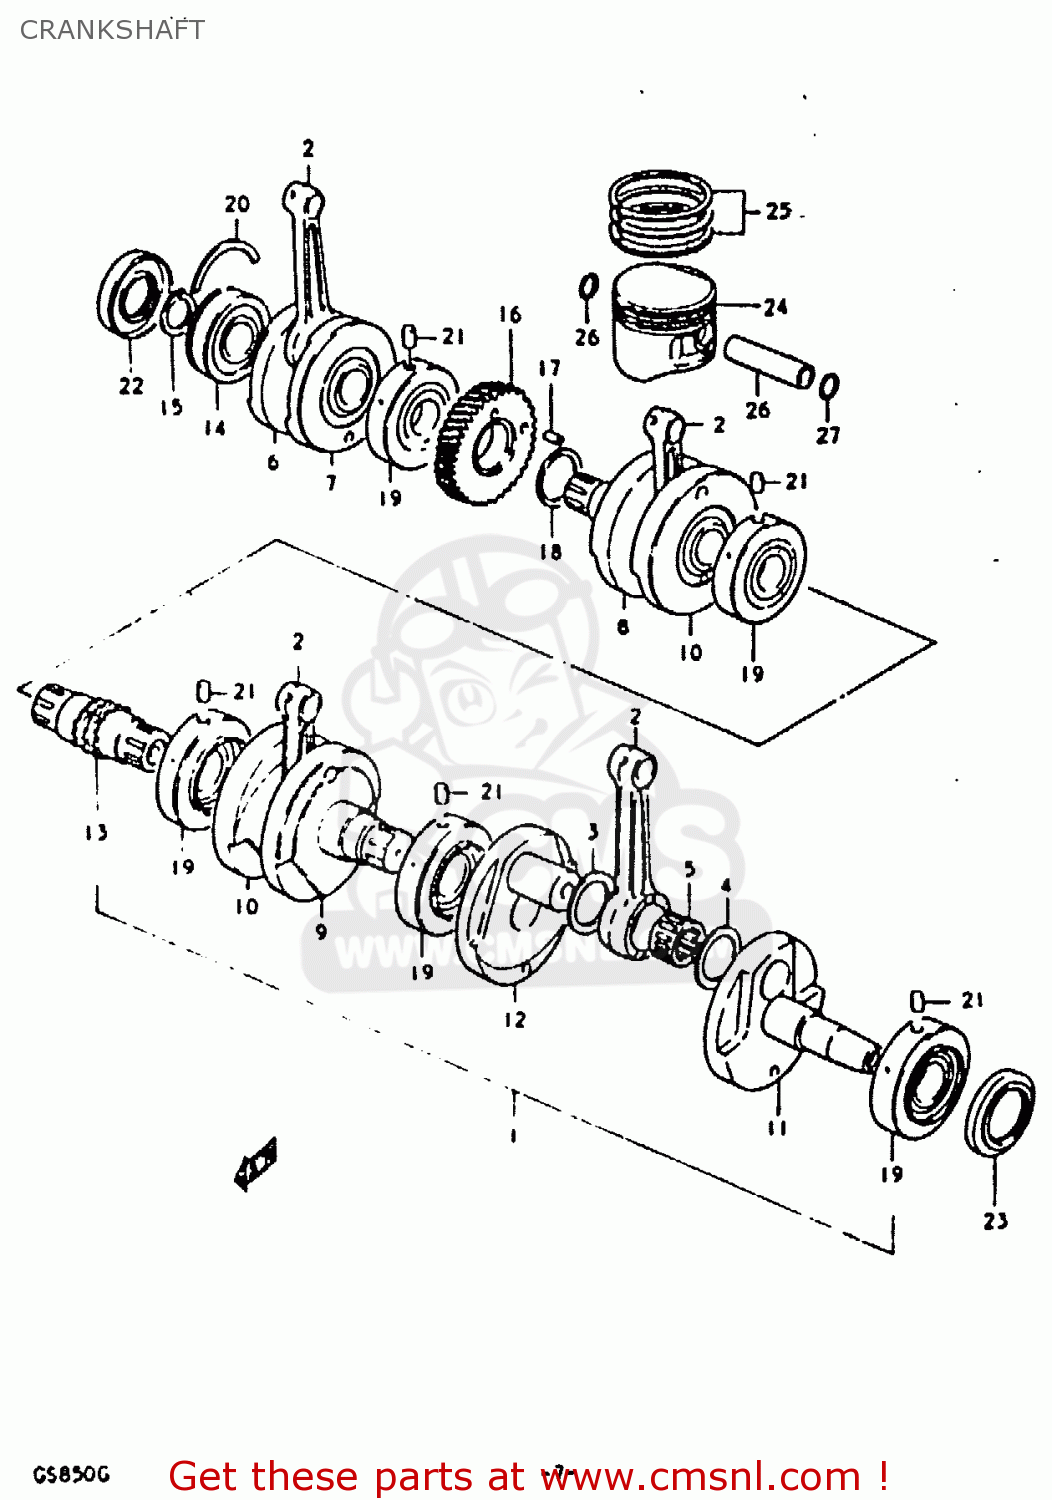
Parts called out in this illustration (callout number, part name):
1	CRANKSHAFT ASSEMBLY
2	CONNECTING ROD
3	WASHER (29X48X2)
4	WASHER (29X48X1)
5	BEARING(29X39X20)
6	CRANKSHAFT
7	WEB,CRANK,RIGHT
8	CRANKSHAFT
9	CRANKSHAFT, MIDDLE LH
10	WEB,CRANK,MIDDLE
11	CRANKSHAFT,LEFT
12	WEB,CRANK,LEFT
13	SHAFT,TIMING CHAIN DRIVE
14	BEARING(30X72X19)
15	CIRCLIP,30MM
16	GEAR,PRIMARY DRIVE
17	PIN
18	WASHER
19	BEARING
20	C RING
21	PIN
22	SEAL,OIL(30X72X11)
23	OIL SEAL
24	PISTON
25	RING SET,PISTON
26	PIN,PISTON
27	CIRCLIP
